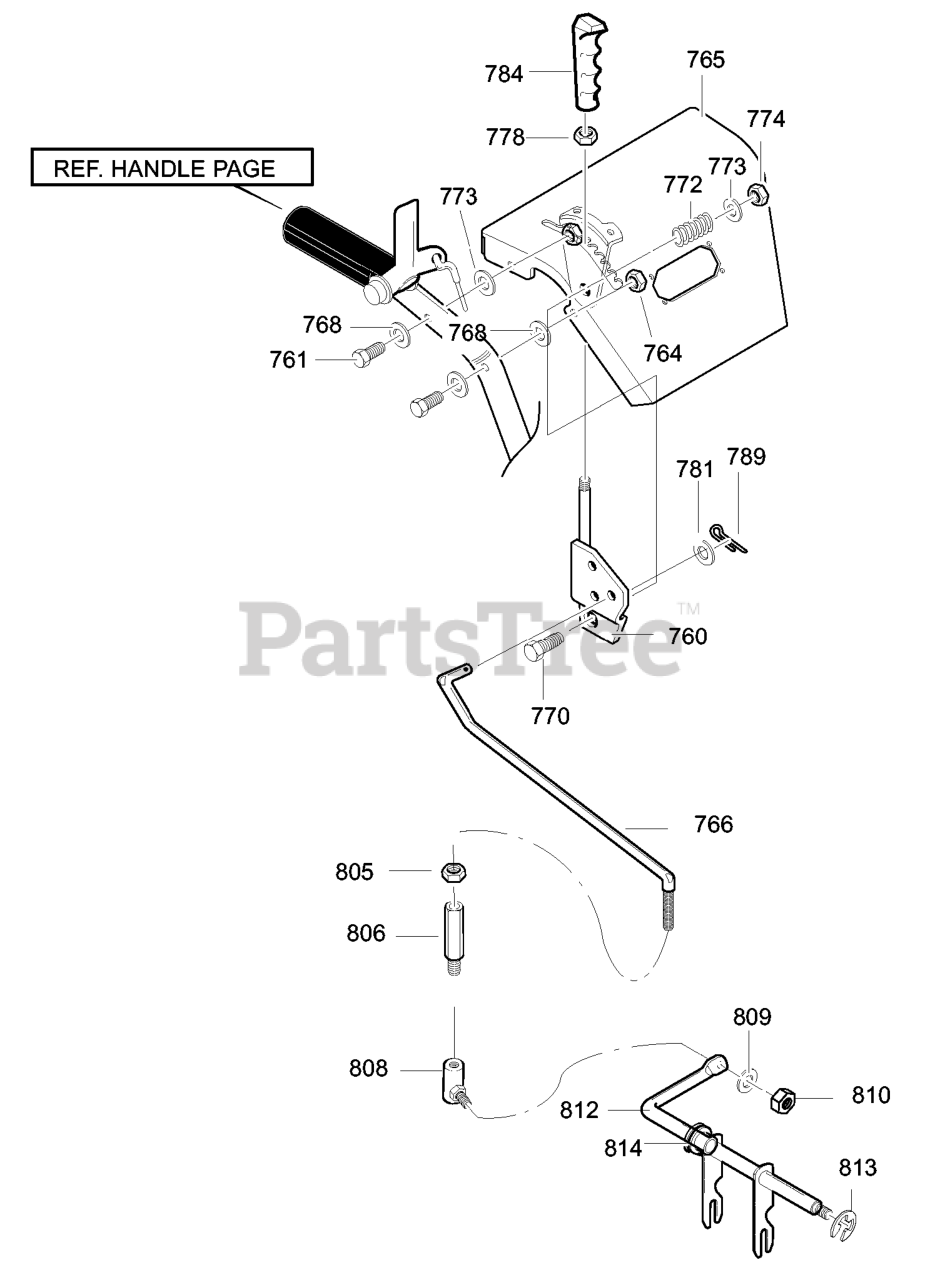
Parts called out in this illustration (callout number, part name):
760	HANDLE ASSY SPD CTRL
761	SCREW, 5/16-18 x 1.75
764	NUT, 5/16-18
765	ASSY. BAYPANEL -LT
766	ROD, SPEED CONTROL
768	WASHER
770	SCREW 3/8-16X2.00
773	FLATWASHER
774	NUT, 3/8-16
778	NUT, 3/8-16
781	FLATWASHER
784	GRIP, HANDLE
789	PIN, COTTER
805	NUT, 5/16-18
806	ADAPTER, SPEED ROD -YZ
808	BALLJOINT, STEEL -YZ
809	WASHER
810	NUT, 5/16-18
812	ROD, ASSY YOKE
813	RING, RETAINER
814	BEARING, FLANGE
